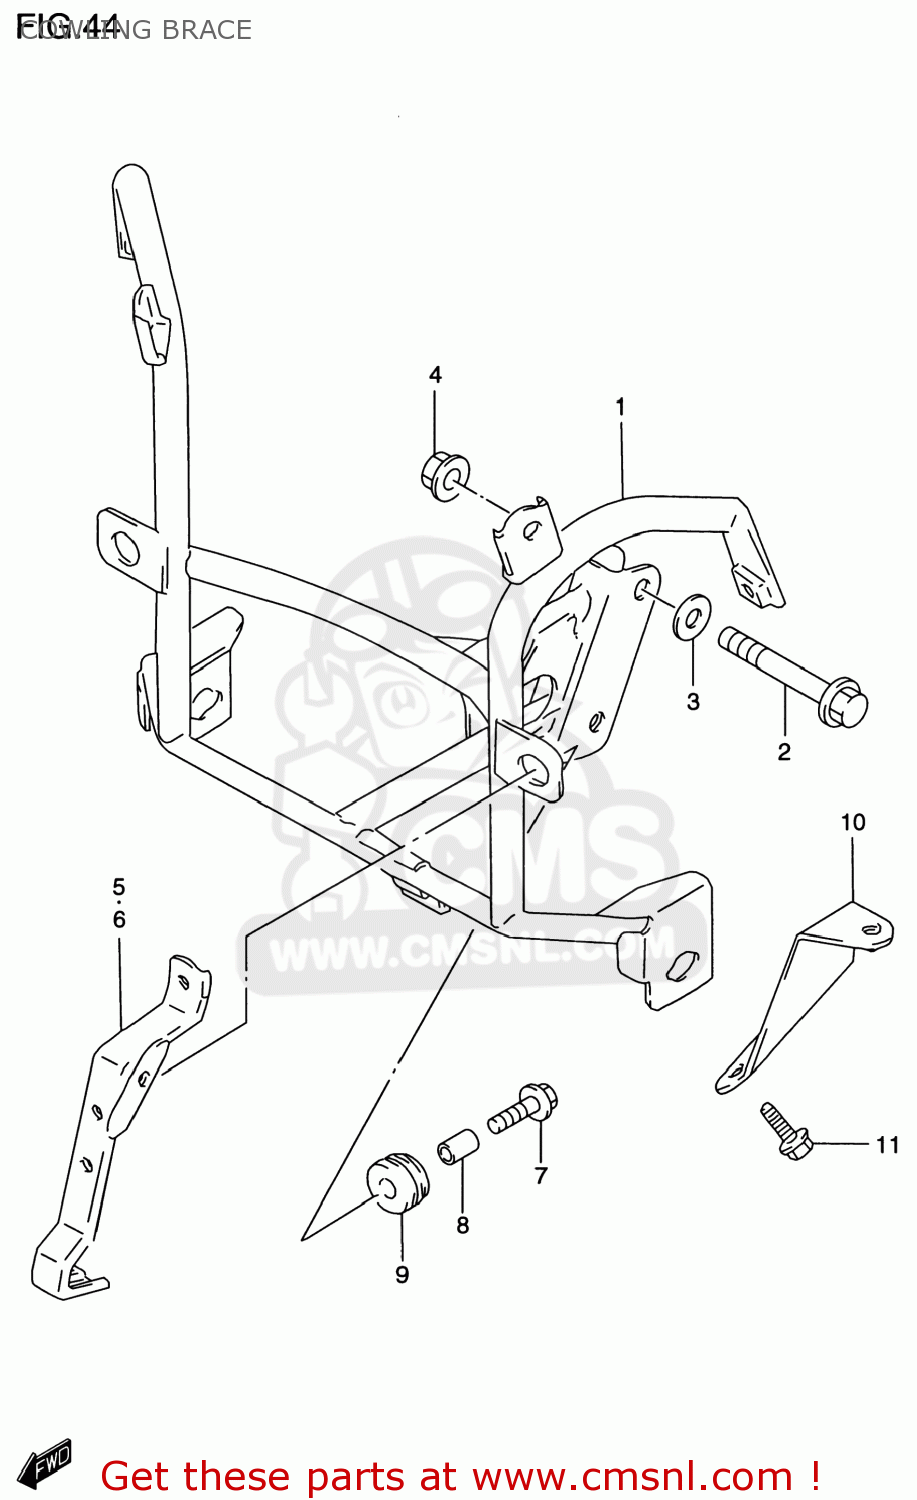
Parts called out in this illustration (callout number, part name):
1	BRACE,COWLING
2	BOLT(8X40)
3	WASHER
4	NUT
5	BRACKET,HEADLAMP,R
6	BRACKET,HEADLAMP,L
7	BOLT(6X25)
8	SPACER(6.5X9X10)
9	CUSHION
10	BRACKET,COWLING RR,R
11	BOLT
